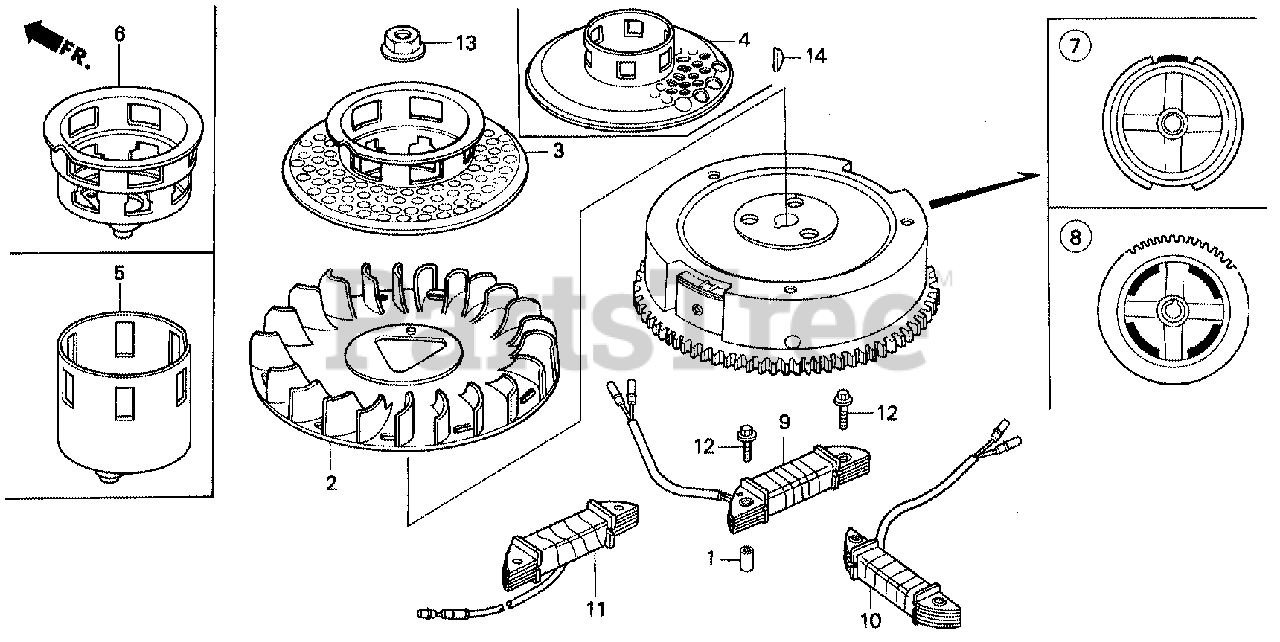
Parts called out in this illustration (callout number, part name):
1	COLLAR, EXTENSION
2	FAN, COOLING
3	PULLEY, STARTER
4	PULLEY, STARTER (SCREEN GRID)
7	FLYWHEEL
13	NUT, SPECIAL (16MM) (1)
13	NUT, SPECIAL (16MM)
14	KEY, SPECIAL WOODRUFF (25X18)
